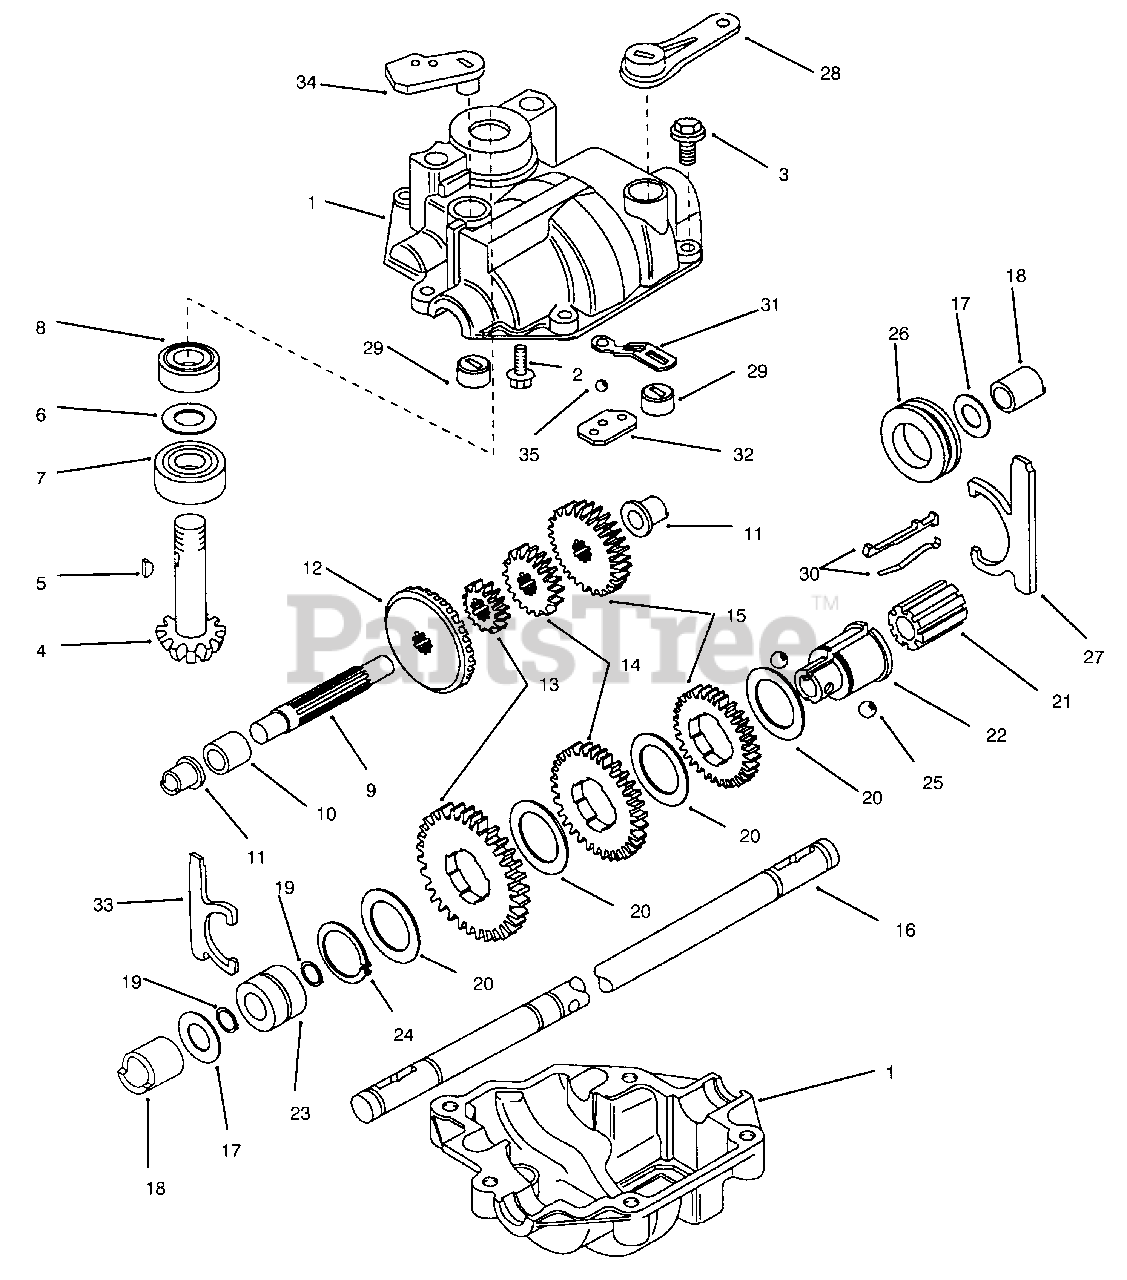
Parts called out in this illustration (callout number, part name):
1	Kit Upper & Lower Case (Incl. Sealant)
2	Screw-Tapping
3	Screw-Tapping
4	Shaft-Input
5	Key-Woodruff
7	Bearing-Lower
8	Bearing-Upper
9	Kit-Shaft, Reduction (Incl. Ref. No.10-11)
11	Bushing Set
12	Ring Gear
13	Gear Set
14	Gear Set
15	Gear Set
16	Kit-Axle Shaft (Incl. Ref. No.17-19)
18	Bushing Set
19	Ring-Snap
21	Key-Holder
22	Collar-Shift
24	Ring-Snap
25	Ball
26	Collar-Sliding
27	Fork-Shift
28	Arm-Shift
29	Support-Fork
30	Spring & Key-Shift
33	Fork-Clutch
34	Arm-Clutch
